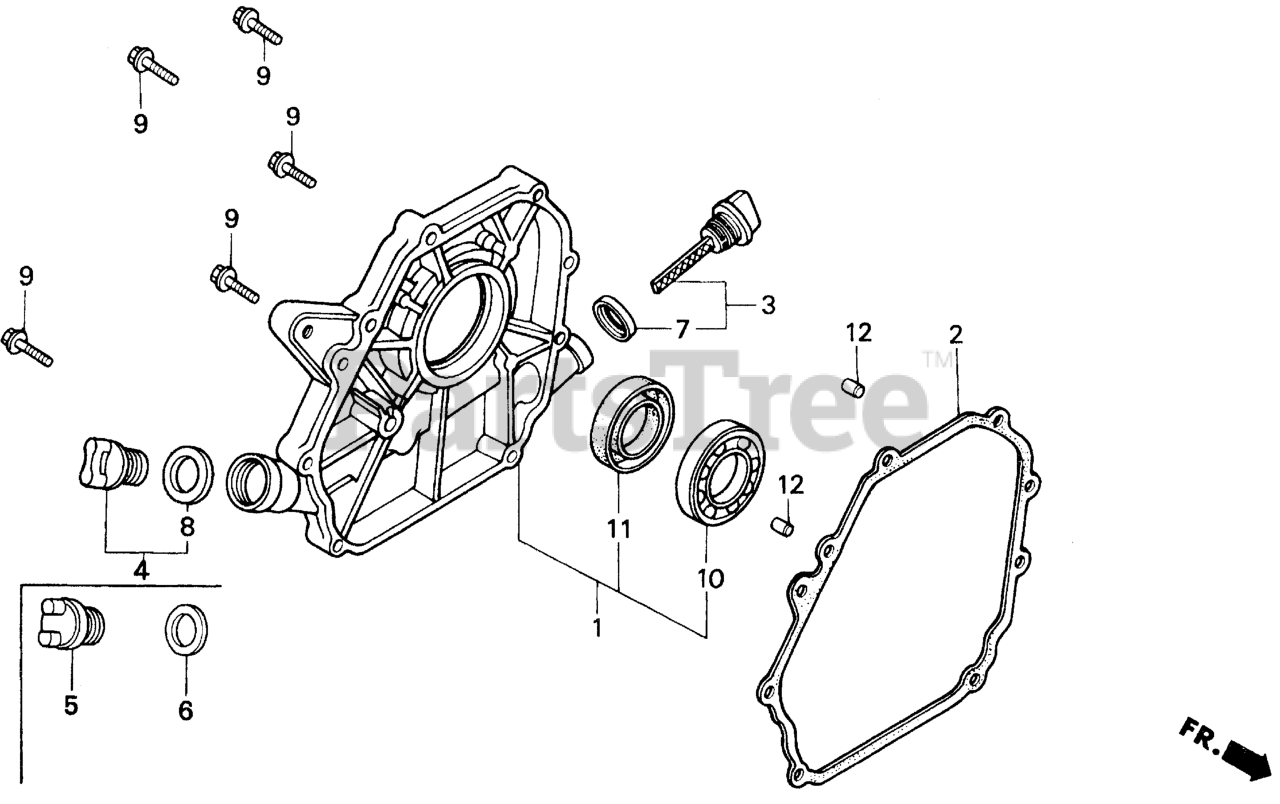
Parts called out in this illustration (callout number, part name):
1	COVER ASSY., CRANKCASE
2	GASKET, CASE COVER
3	CAP ASSY., OIL FILLER
4	CAP ASSY., OIL FILLER
5	CAP, OIL FILLER
6	GASKET, OIL FILLER CAP Use from Engine SN 1391010.
7	GASKET, OIL FILLER CAP
8	GASKET, OIL FILLER CAP
9	BOLT, FLANGE (6X28) (CT200) Use up to Engine SN 1530314.
10	BEARING, RADIAL BALL (62/22)
11	OIL SEAL (22X41X6)
12	PIN A, DOWEL (8X14)
